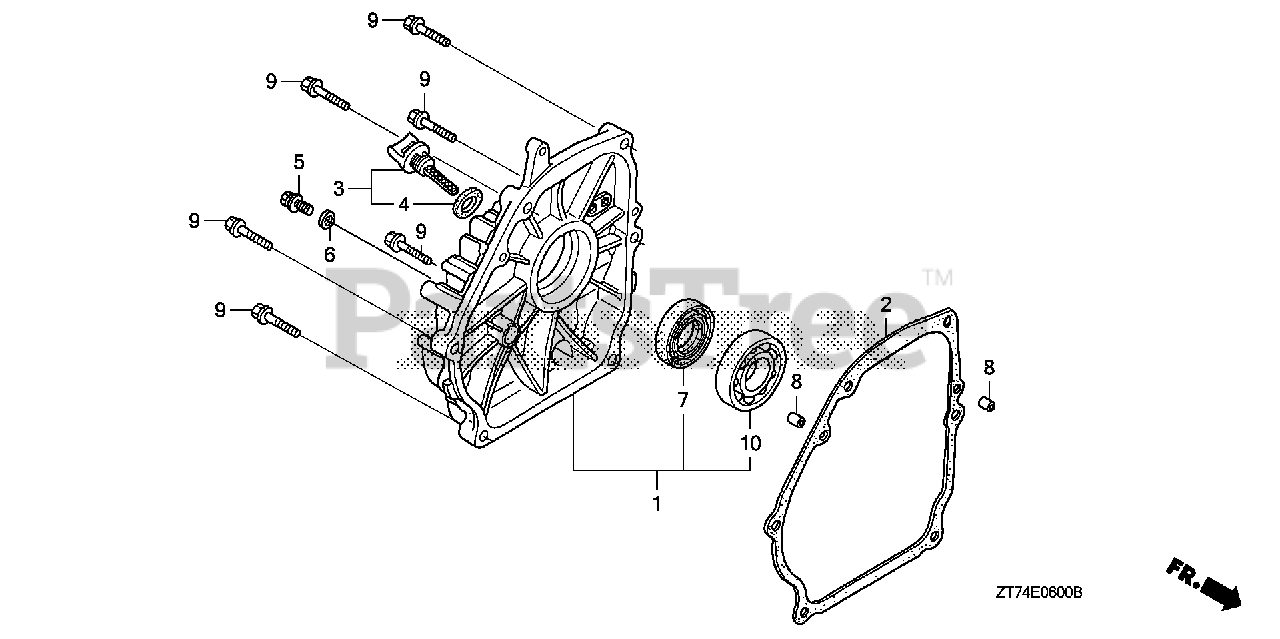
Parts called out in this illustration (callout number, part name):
1	COVER, CRANKCASE
2	GASKET, CASE COVER (NON-ASBESTOS)
3	CAP ASSY., OIL FILLER
4	GASKET, OIL FILLER CAP
5	BOLT, DRAIN PLUG
6	WASHER, DRAIN PLUG (10.2MM)
7	OIL SEAL (25X41X6)
8	PIN A, DOWEL (8X14)
9	BOLT, FLANGE (8X32)
10	BEARING, RADIAL BALL (6205)
